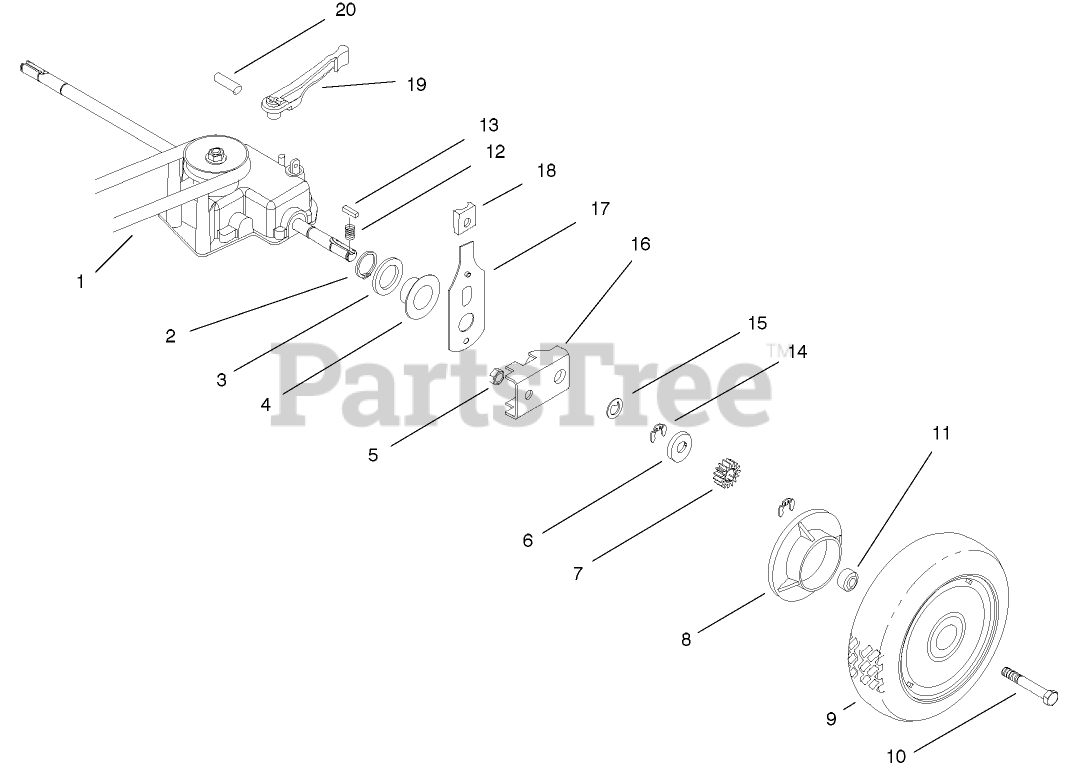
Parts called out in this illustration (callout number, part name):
1	V-BELT
2	RING-RETAINING
3	WASHER
4	CAP-END
5	NUT-LOCK, CONE
6	WASHER-THRUST, OUTER
7	GEAR-PINION
8	COVER-WHEEL
10	SCREW-HH
11	SPACER-COVER, WHEEL
12	SPRING-COMPRESSION
14	RING-RETAINING
15	WASHER-THRUST, OUTER
16	PIVOT ARM ASM
17	REAR SPRING ARM ASM
18	KNOB-ARM
19	LEVER-SHIFT
20	PIN-SPRING
